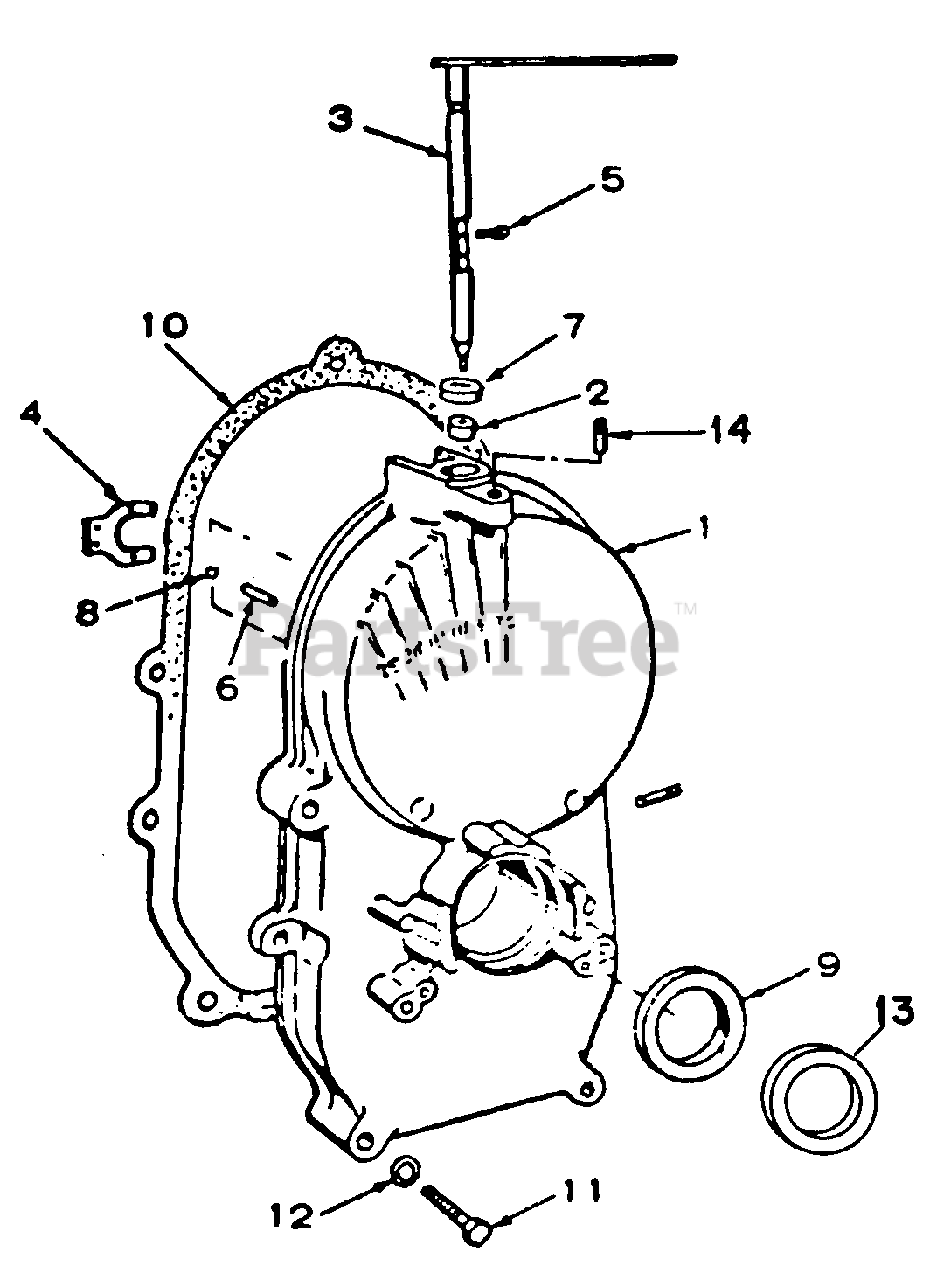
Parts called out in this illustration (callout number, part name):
1	Case Assy, Gear
2	Bearing, Upper Gov Shaft Sleeve
3	Shaft Assy, Governor
4	Yoke, Governor Shaft
5	Screw, No. 8 X 3/8 Znp P/Hdcr Mach
7	Seal, Gov Shaft Oil
8	Bearing, Ball
10	Gasket, Gear Case
11	Bolt, 5/16 X 1-3/4 Phc Type 8
12	Washer, Gear Case Mounting
13	Not used in this application
14	Tube, Vacuum Port
